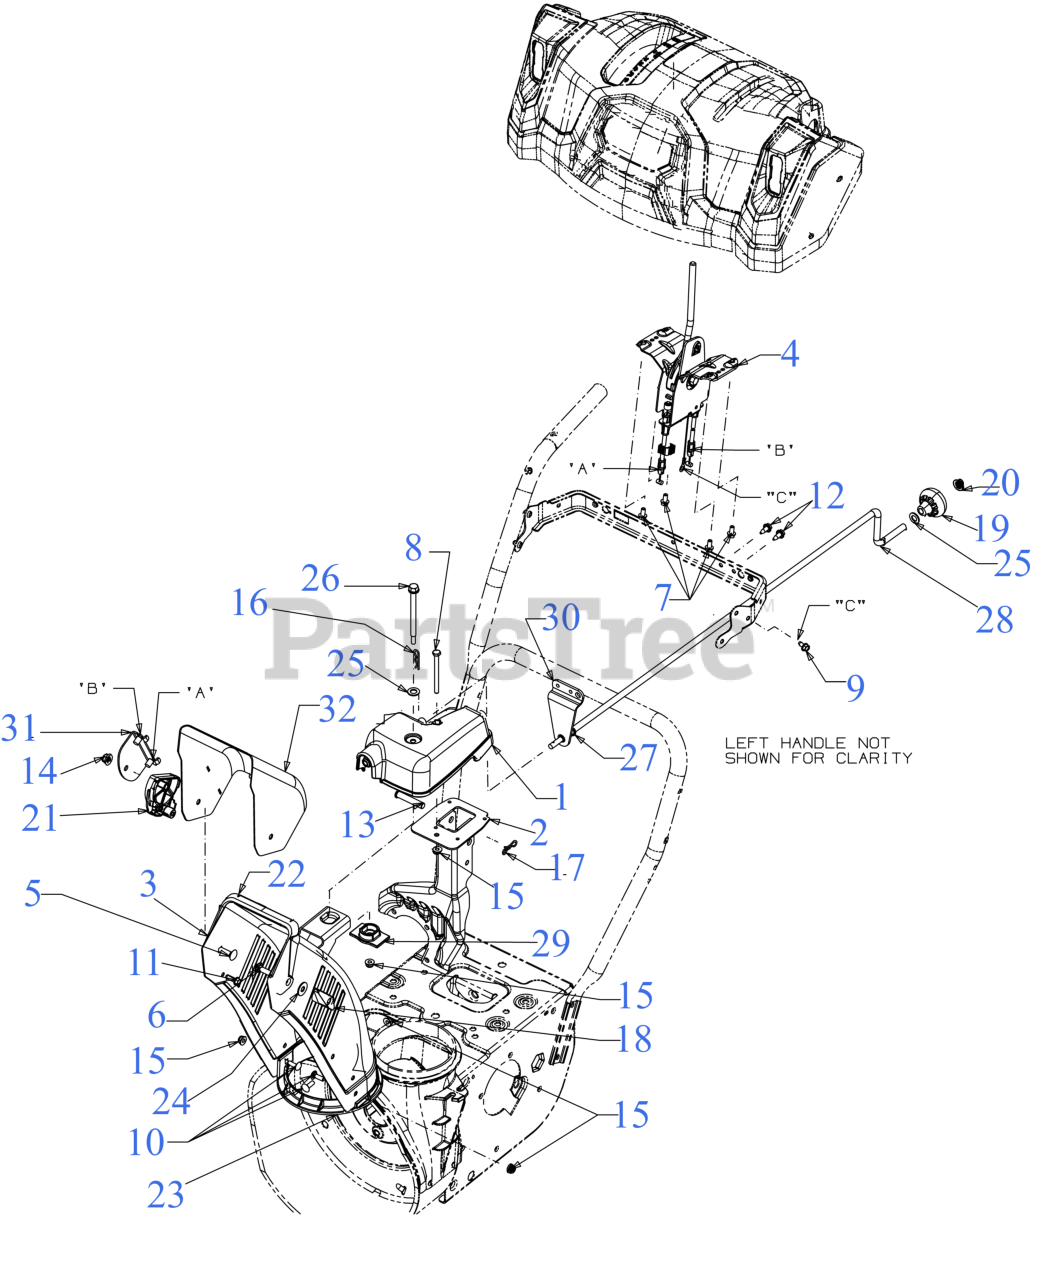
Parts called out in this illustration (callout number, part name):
1	2-WAY CHUTE ROTATE GEARBOX
2	CHUTE SUPPORT ASSEMBLY
3	STEEL CHUTE
4	CHUTE CONTROL ASSEMBLY
5	CARRIAGE BOLT 5/16-18 x 1.50
6	CARRIAGE BOLT 5/16-18 x 1.00
7	HEX SCREW 1/4-15 x .50
8	SCREW 1/4-20 x 3.0 GR5
9	SCREW 1/4-20 X.500
10	SCREW 1/4-20 x .75 GR5
11	SCREW 1/4-15 x .750
12	SCREW 1/4-20X.625
13	CLEVIS PIN 3/8 x 1.87
14	FLANGE LOCK NUT 5/16-18
15	FLANGE LOCK NUT
16	INTERNAL COTTER PIN
17	BOW TIE COTTER PIN 1/4-5/16
18	WING KNOB NUT
19	SHIFT KNOB
20	PUSH NUT
21	CHUTE TILT GUIDE
22	UPPER CHUTE ADAPTER
23	CHUTE BASE 5.0 DIA
24	FLAT WASHER
25	FLAT WASHER
26	SHOULDER SCREW
27	BUSHING .380 ID
28	CHUTE CRANK .375 DIA x 31"
29	HELICAL GEAR CHUTE ADAPTER
30	ROD SUPPORT BRACKET
32	UPPER STEEL CHUTE (REMOTE TILT)
